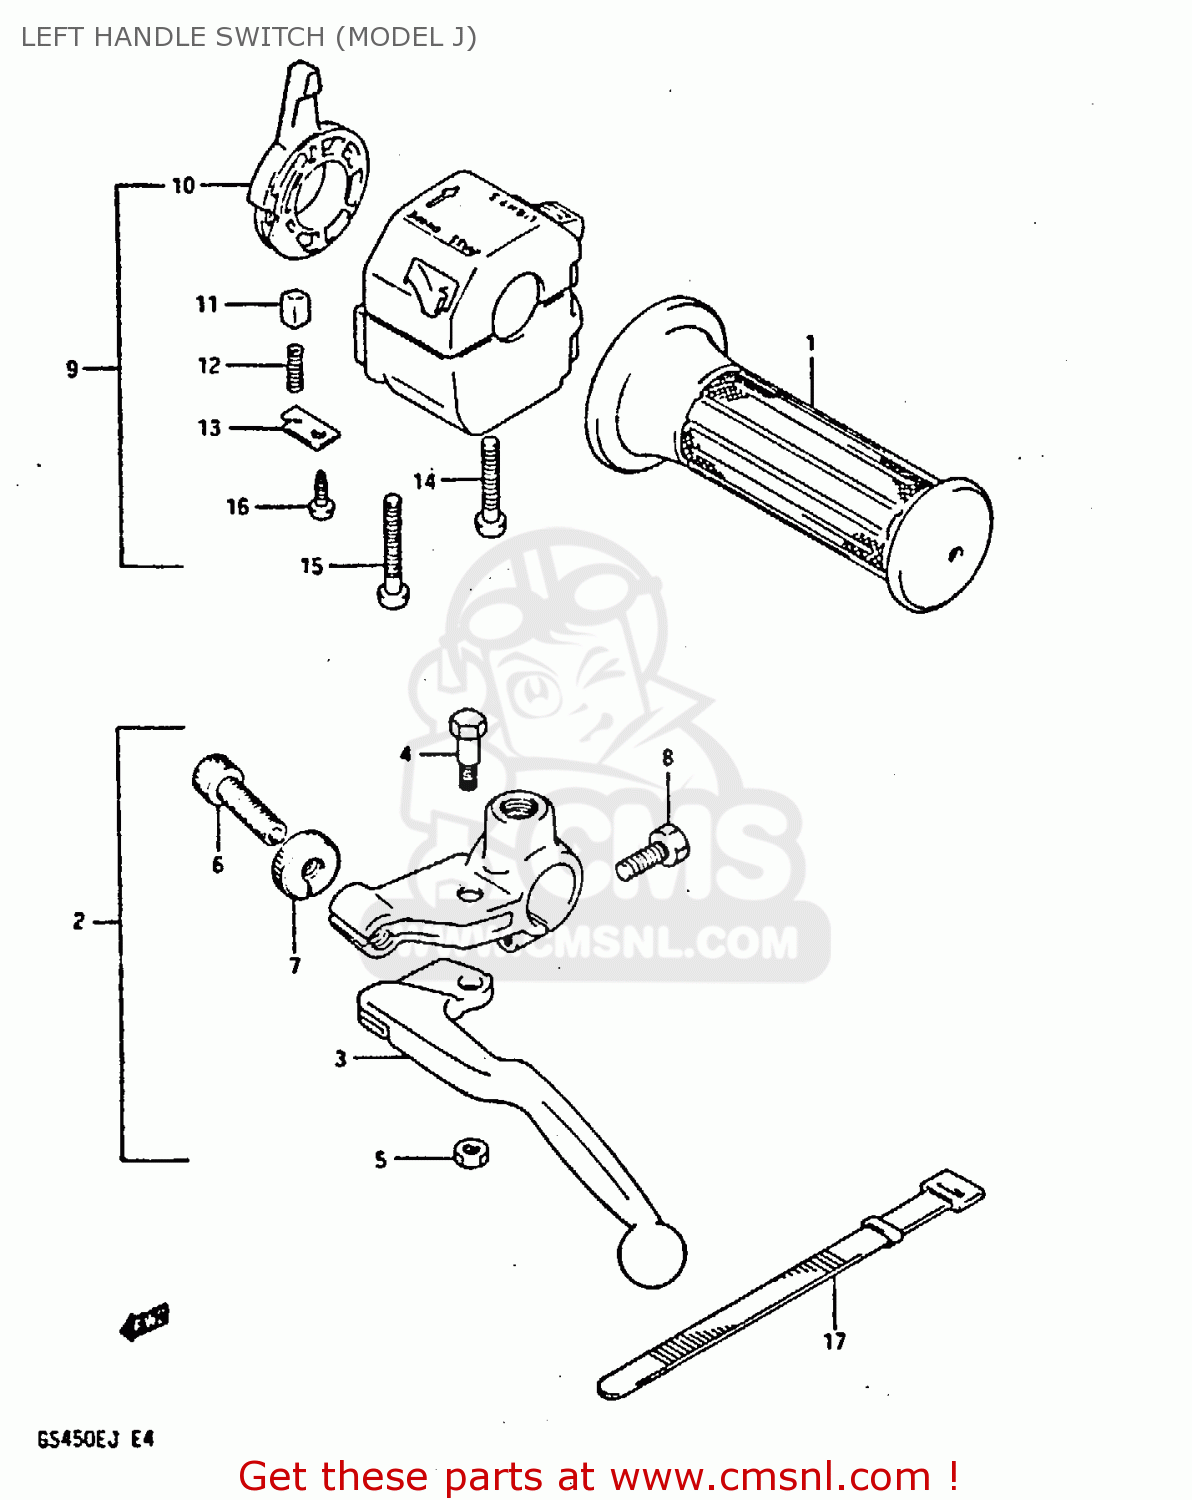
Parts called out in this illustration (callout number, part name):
1	GRIP,L
2	LEVER ASSY, CLUTCH
3	LEVER,CLUTCH
4	BOLT,LEVER
5	NUT
6	ADJUSTER,CABLE
7	NUT,CABLE ADJUSTER
8	BOLT
9	SWITCH ASSEMBLY,HANDLE,LEFT
10	LEVER,CHOKE
11	PIECE,SLIDE
12	SPRING
13	PLATE
14	SCREW
15	SCREW, 5X45
16	SCREW
17	CLAMP(L:120)
